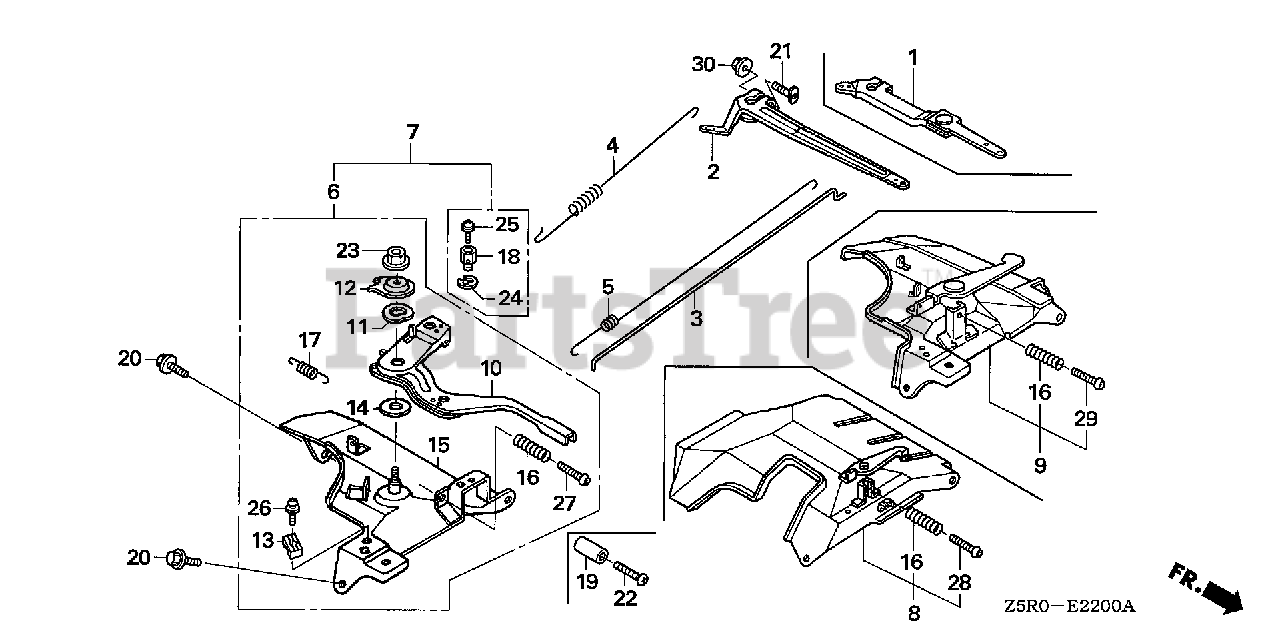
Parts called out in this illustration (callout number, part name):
1	ARM, GOVERNOR
3	ROD, GOVERNOR
4	SPRING, GOVERNOR (L=137.5MM)
5	SPRING, THROTTLE RETURN
8	CONTROL ASSY.
16	SPRING, CONTROL ADJUSTING
20	BOLT, FLANGE (6X12) (CT200)
21	BOLT, GOVERNOR ARM
28	SCREW, PAN (5X35)
30	NUT, FLANGE (6MM)
